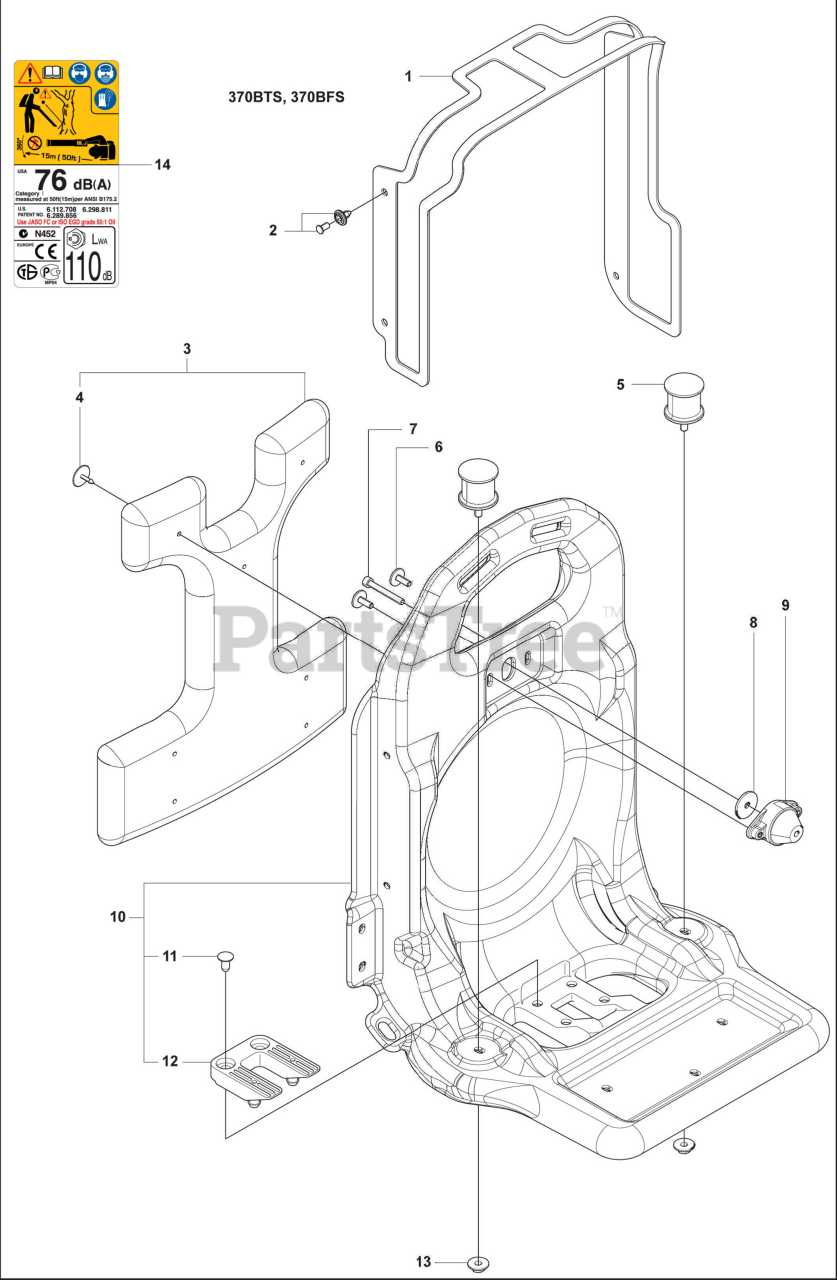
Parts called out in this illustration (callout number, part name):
2	CLIP
3	Pad
4	Clip
5	Damper
7	Bolt
9	Upper Damper
11	Clip
13	Nut
14	LABEL
